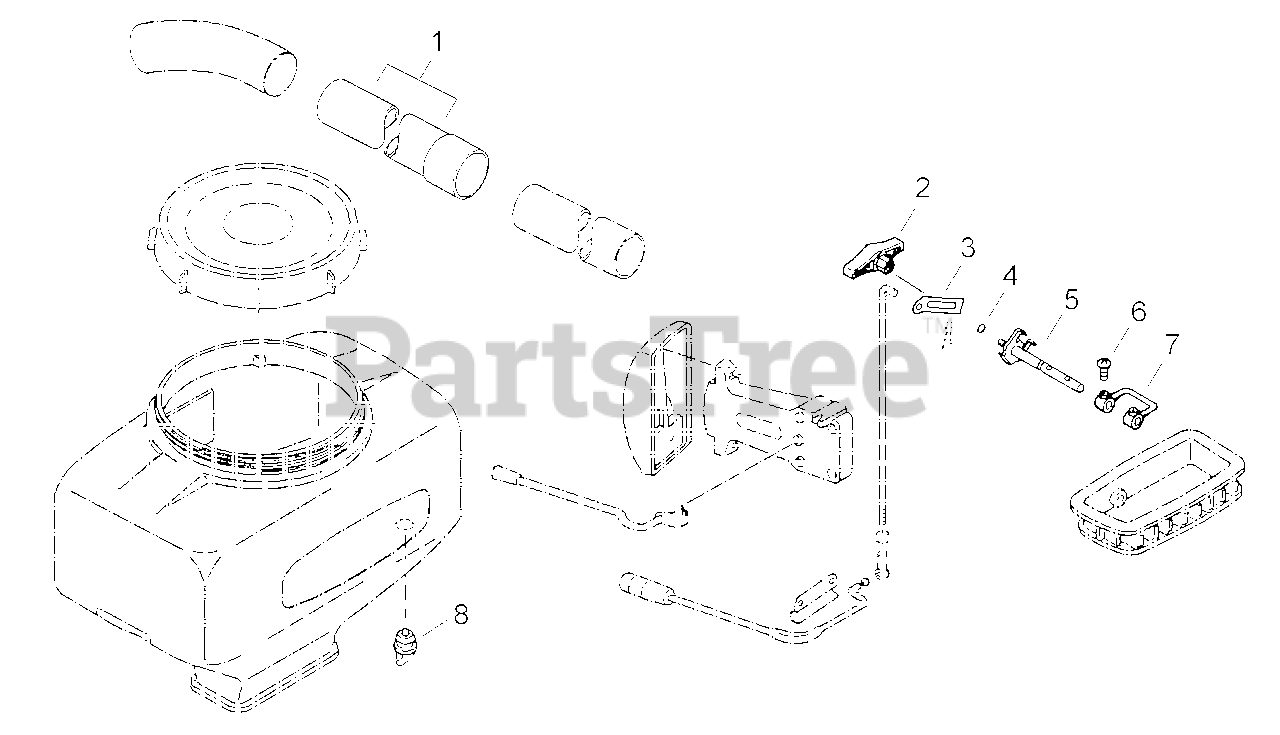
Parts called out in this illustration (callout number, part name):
1	SHUTTER ASSY
2	O-RING - 4
3	WINGNUT - 5
4	STABILIZER
5	STUD - 5X50
6	SCREW - 4X10
9	SHAFT, SHUTTER
11	SHUTTER, RATE CONTROL
12	SCREW - 4X14
14	MOUNT, SHUTTER
15	GASKET
16	ADAPTOR, DUST OUTLET
